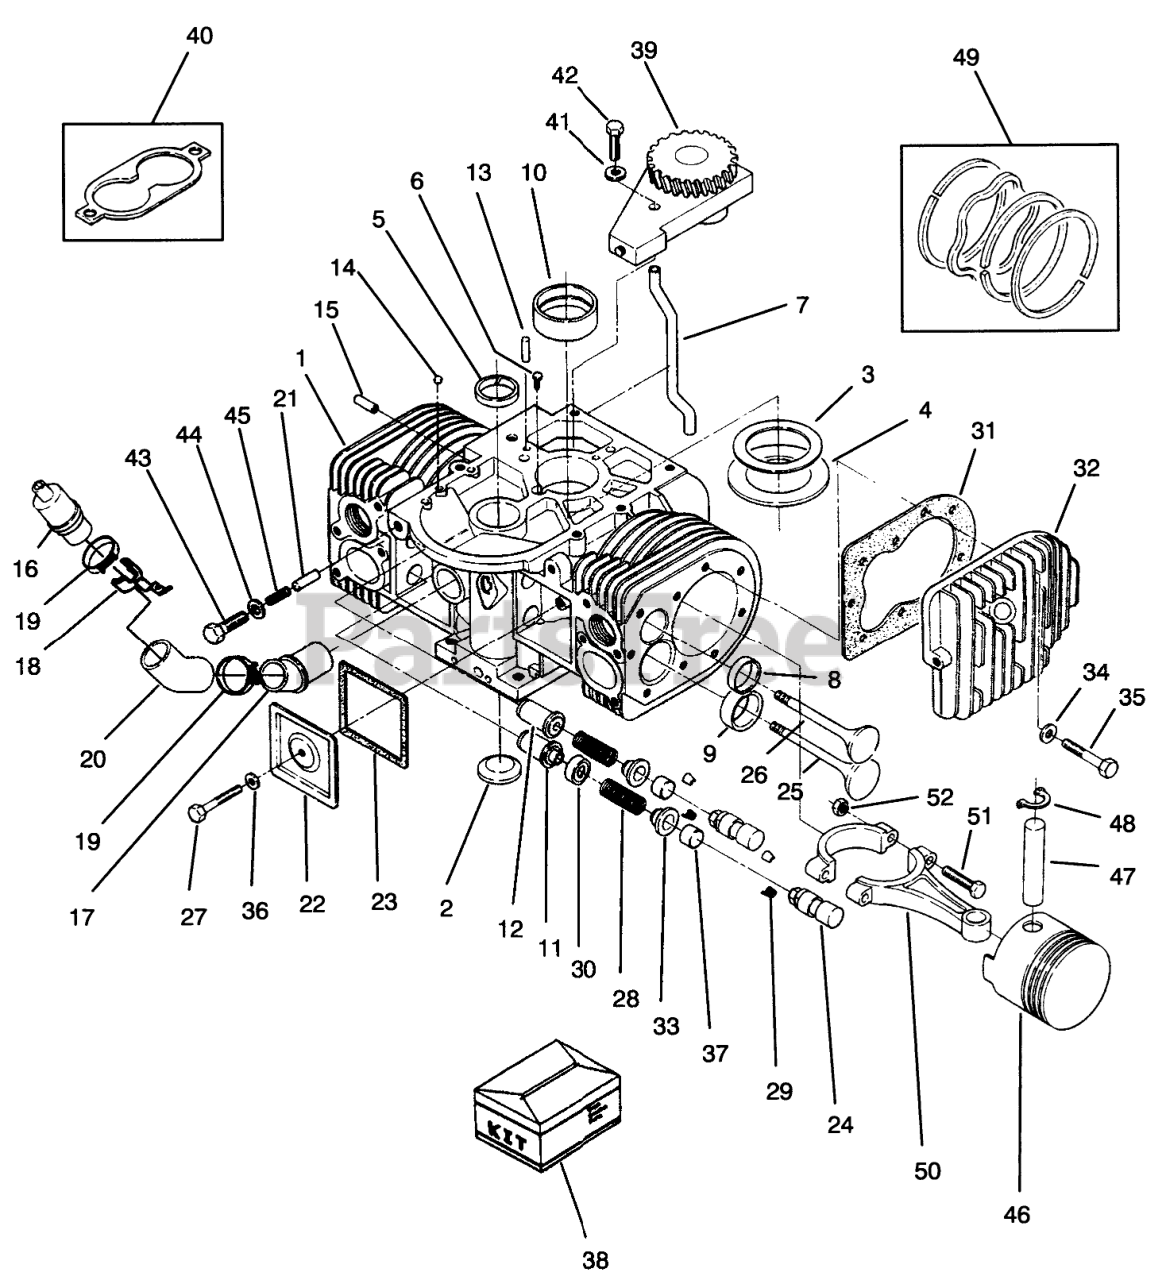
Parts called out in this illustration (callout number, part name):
1	BLOCK-ASS'Y CYLINDER
2	Plug
3	PISTON
4	WASHER
5	SLEEVE-BEARING
6	Screw
7	OIL TUBE
8	Standard
9	SEAT-INT VALVE (STD)
10	Bearing-Up Crankshaft Std
11	Guide-Intake Valve
12	Guide-ExhaustValve
13	Pin
14	PLUG-CORE HOLE
15	TUBE-PORT, VACUUM
16	Breather Tube
17	BREATHER-ADAPTER
18	BREATHER-MTG BRKT
19	HOSE-CLAMP
20	BREATHER-HOSE
21	DOWEL-PIN PLUG
22	Cover-Valve
23	LOCK (SET OF 2)
24	TAPPET
25	Intake Valve
26	Exhaust Valve
27	HHCS 1/4-20 X 1 3/4
28	Spring
29	VALVE SPRING LOCK
30	Seal
31	GASKET
32	Side-Left
33	Washer
34	WASHER
35	Bolt
36	WASHER
37	Cap-Valve
38	ENGINE GASKET KIT
39	Pump-Oil
40	Kit-Oil Pump Gasket
41	Washer
42	Bolt
43	SCREW-HH
44	WASHER
45	SPRING
46	Standard
47	Pin-Piston
48	Piston Pin
49	RING/PISTON KIT
50	CONNECTING ROD W/NUT
